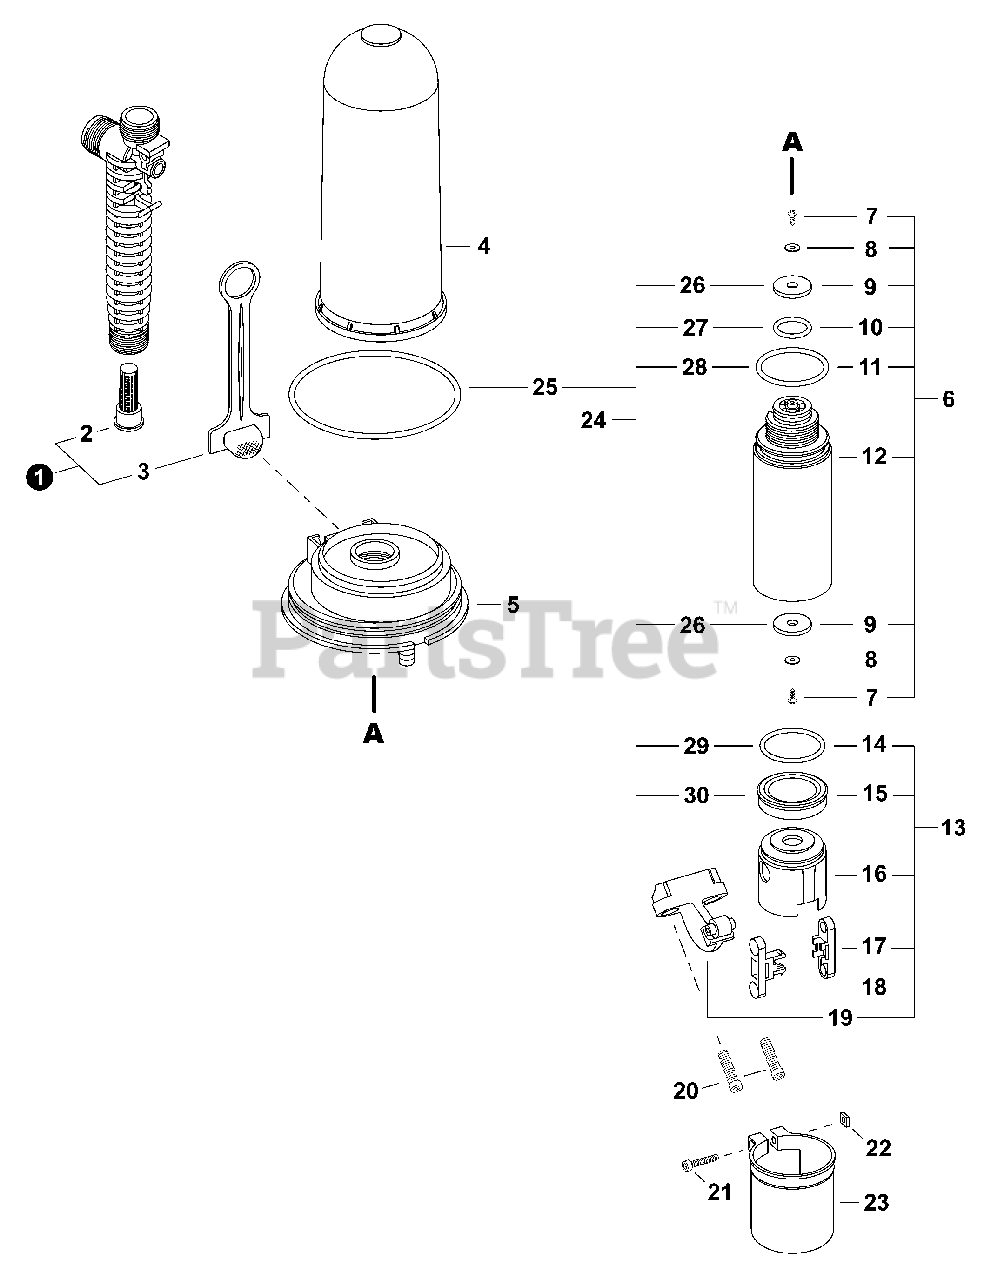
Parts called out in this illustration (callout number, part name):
1	FILTER KIT
2	FILTER, SPRAY GUN
3	FILTER, IN-TANK
4	CHAMBER, PRESSURE
5	BASE, PRESSURE CHAMBER
6	CYLINDER ASSY, PISTON
7	SCREW, CYLINDER
8	WASHER, CYLINDER
9	SEAL, VALVE
10	O-RING, CYLINDER - SMALL
11	O-RING, CYLINDER - LARGE
12	CYLINDER, PISTON
13	PISTON ASSY
14	SPRING, SEAL
15	SEAL, PISTON
16	PISTON
17	ROD, CONNECTING (A)
18	ROD, CONNECTING (B)
19	LEVER, PIVOT
20	SCREW, LEVER
23	CAP, DUST
24	REPAIR KIT, PUMP
25	O-RING, PRESSURE CHAMBER
26	SEAL, VALVE
27	O-RING, CYLINDER - SMALL
28	O-RING, CYLINDER - LARGE
29	SPRING, SEAL
30	SEAL, PISTON
